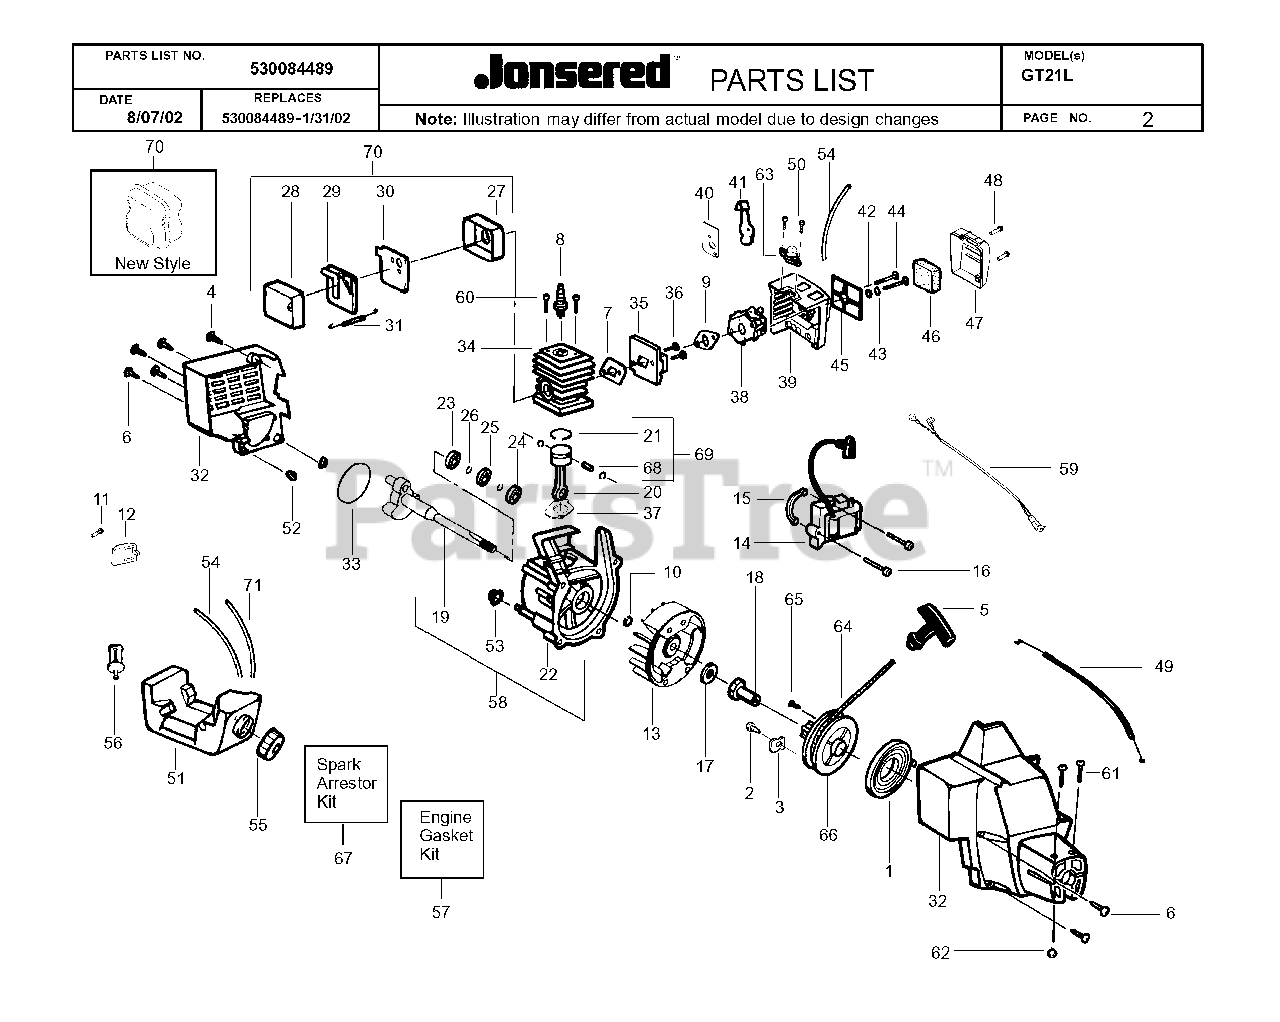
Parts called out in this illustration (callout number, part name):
1	STARTER SPRING
5	HANDLE-STARTER
6	SCREW - SHROUD
7	GASKET KIT
8	PLUG-SPARK (RCJ-6Y)
9	GASKET KIT
10	RETAINING RING
11	SCREW-8-18 X 5/18(RECES
13	FLYWHEEL
14	IGNITION MODULE
15	SPACER - IGNITION MODULE
17	WASHER FLAT
18	COUPLING-DRIVE
20	CONNECTING ROD ASSEMBLY
21	PISTON RING
22	ASSY-CRANKCASE
23	BEARING
25	SEALING RING
27	MUFFLER BODY
28	MUFFLER COVER
29	MUFFLER BAFFLE - EXIT
30	MUFFLER BAFFLE - FIRST
33	GASKET KIT
34	CYLINDER
36	SCREW - CARB. ADAPTOR
37	GASKET KIT
38	CARBURETOR
40	CHOKE PLATE
41	CHOKE SHUTTER
43	CHOKE SPACER
45	FILTER PLATE
46	AIR FILTER FOAM
47	AIR FILTER COVER
49	THROTTLE KIT
51	TANK UNIT
52	SHROUD ISOLATOR
53	CRANKCASE ISOLATOR
54	KIT-LINE(FUEL)
55	CAP ASSY W/ RETAINER
56	FUEL PICK-UP ASSY
57	GASKET KIT
58	CRANKCASE/CRANKSHAFT ASSEMBLY
59	LEAD WIRE ASSEMBLY
61	SCREW-10-24 X 1-3/8 (UN
62	LOCKNUT-HEX 10-24
63	AIR PURGE BUBBLE
66	STARTER PULLEY KIT
68	WRIST PIN RET.
69	PISTON KIT
70	KIT-MUFFLER
71	FUEL LINE - PRIM/TNK
530037045	MUFFLER GUARD
